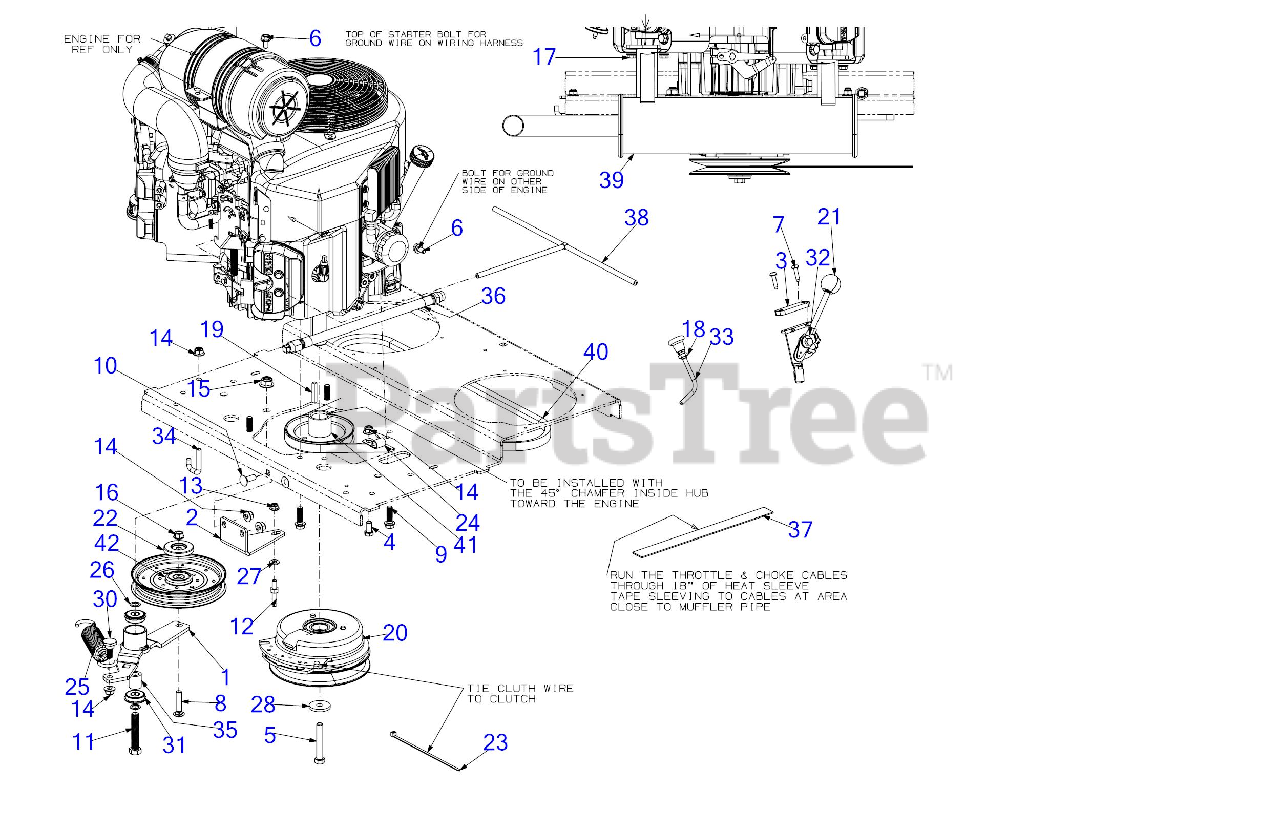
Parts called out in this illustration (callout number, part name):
4	HEX SCREW 3/8-16 x .75
5	SCREW 7/16-20:2.75 GR5
6	SCREW M8 x 1.25 x 16MM GR8.8
7	SCREW 1/4-20 x 1.0
8	CARRIAGE BOLT 3/8-16 x 1.75 GR5
9	SCREW 3/8-16 x 1.25 GR5
10	CARRIAGE BOLT 3/8-16 x 1.00 GR5
11	SCREW 1/2-13 x 2.75 GR5
13	FLANGE LOCK NUT 5/16-18
16	HEX LOCK NUT
17	HEX FLANGE NUT
18	HEX JAM NUT 3/8X24
19	SQUARE KEY 1/4 x 1.50
20	ELECTRIC PTO CLUTCH
20	CLUTCH HARNESS 11.625
22	PULLEY CAP
23	7" CABLE TIE
24	J TYPE CLIP
25	EXTENSION SPRING W/HOOK
26	WASHER .510 x .995
27	FLAT WASHER
28	FLAT WASHER .45 x 1.5 x .172 HT
30	SHOULDER SCREW .625 x .302 x 3/8-16
31	ROLLER BEARING .5X1.37X.44
32	THROTTLE CABLE 59"
33	CHOKE CABLE
34	ROD SPRING HOOK
35	SPACER 0.51 X 0.88 X 1.00
36	OIL DRAIN HOSE
38	ROLLOVER VENT HOSE ASSEMBLY
39	MUFFLER - KAWASAKI 1000
40	TRANSMISSION BELT 61.5
41	PULLEY - PUMP DRIVE
42	IDLER PULLEY
